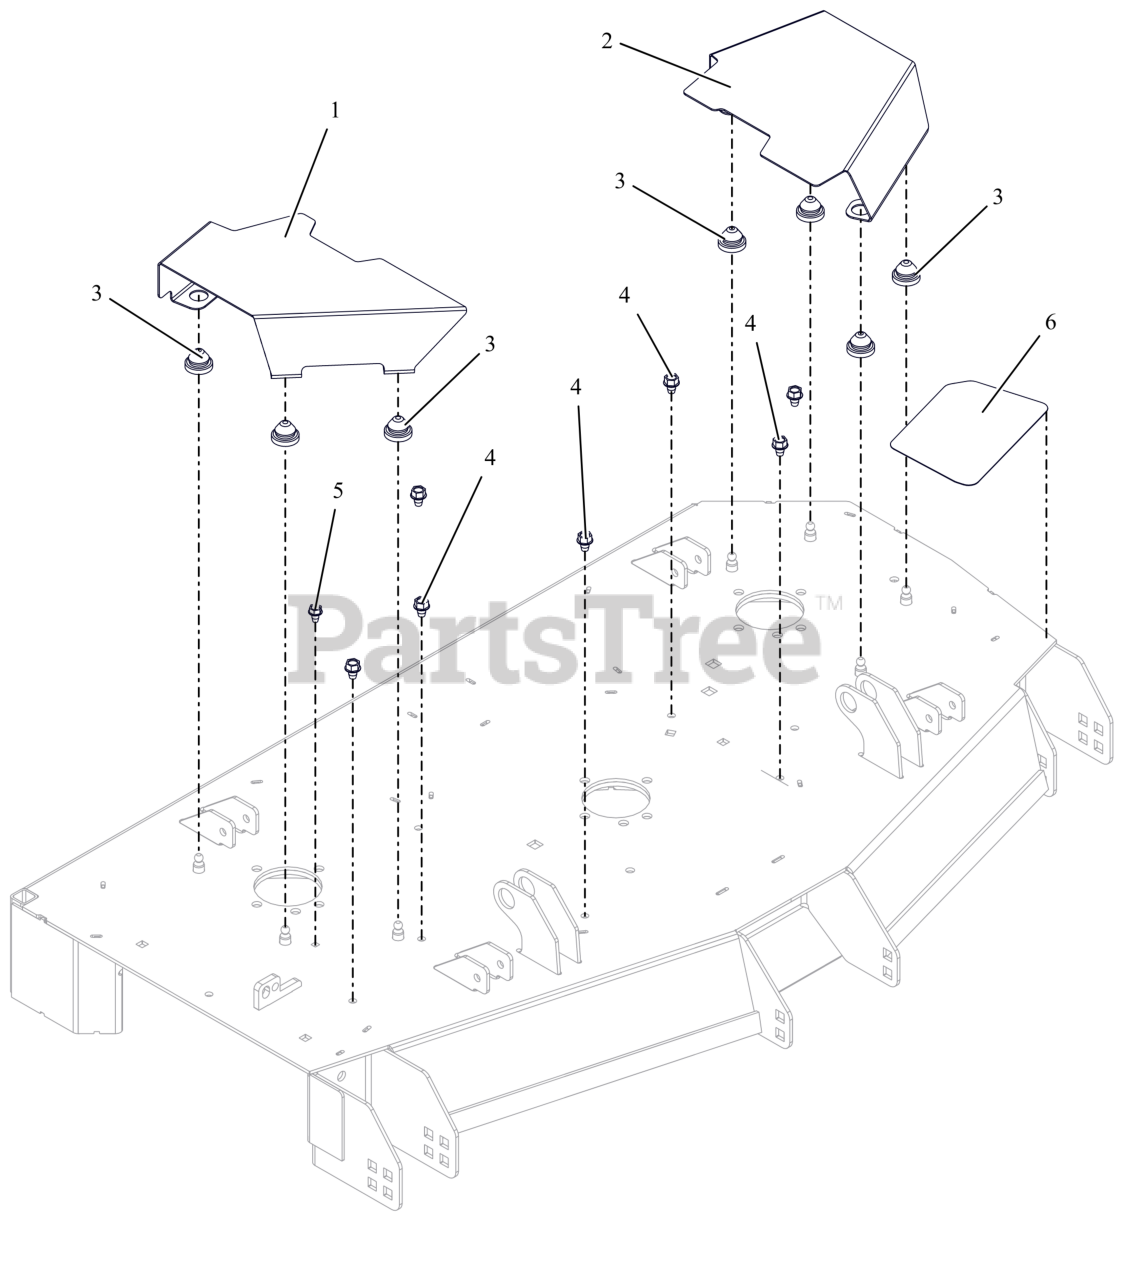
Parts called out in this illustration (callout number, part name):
1	COVER- BELT 48" RIGHT
2	COVER- BELT 48" LEFT
3	COUPLING, RUBBER PUSH-IN
4	SCR,TAP .375-16X.50 HWH TR ZCC
5	SCR,TAP .312-18X.50 HWH TR ZCC
6	GRIP, STEP ANTI SKID HD XF3
